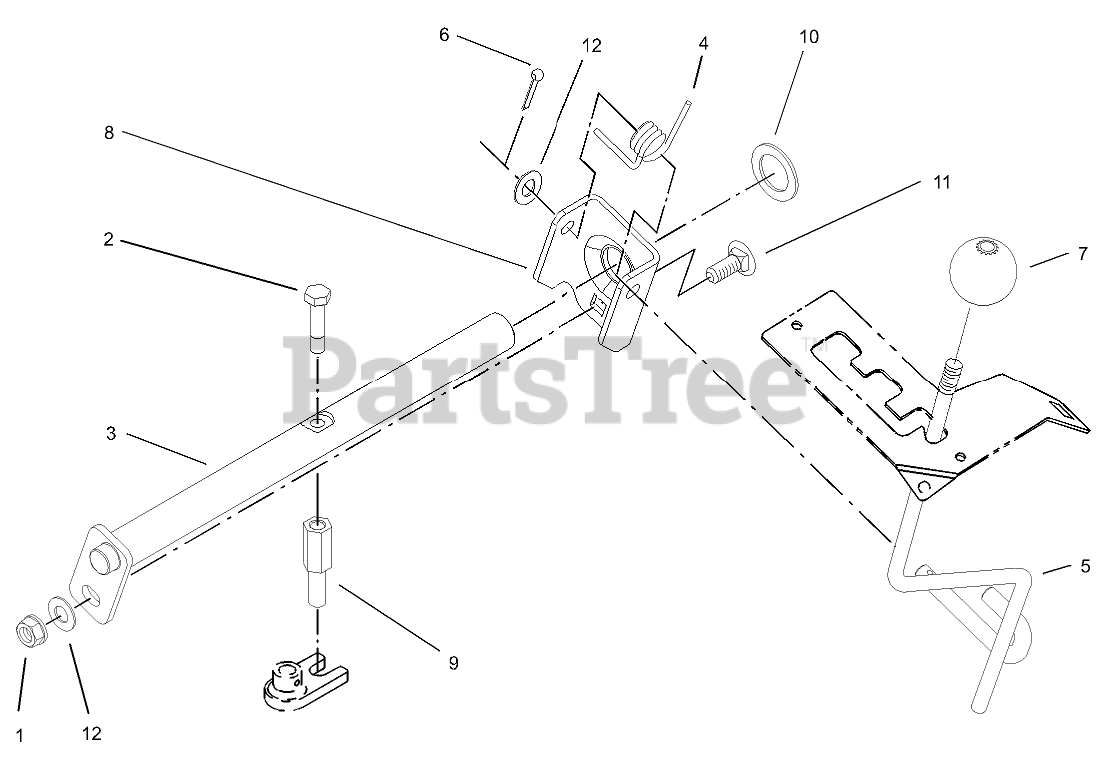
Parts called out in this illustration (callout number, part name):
1	NUT-LOCK, NI
2	SCREW-THREAD LOCKING
3	SHIFT ROD ASM
4	SPRING-TORSION
5	LEVER-SHIFT
6	PIN-COTTER
7	KNOB-HI / LO SHIFT
8	BRACKET-PIVOT
9	ROD-PIVOT, SHIFT
10	SPACER
11	SCREW-CARR
12	WASHER-FLAT
